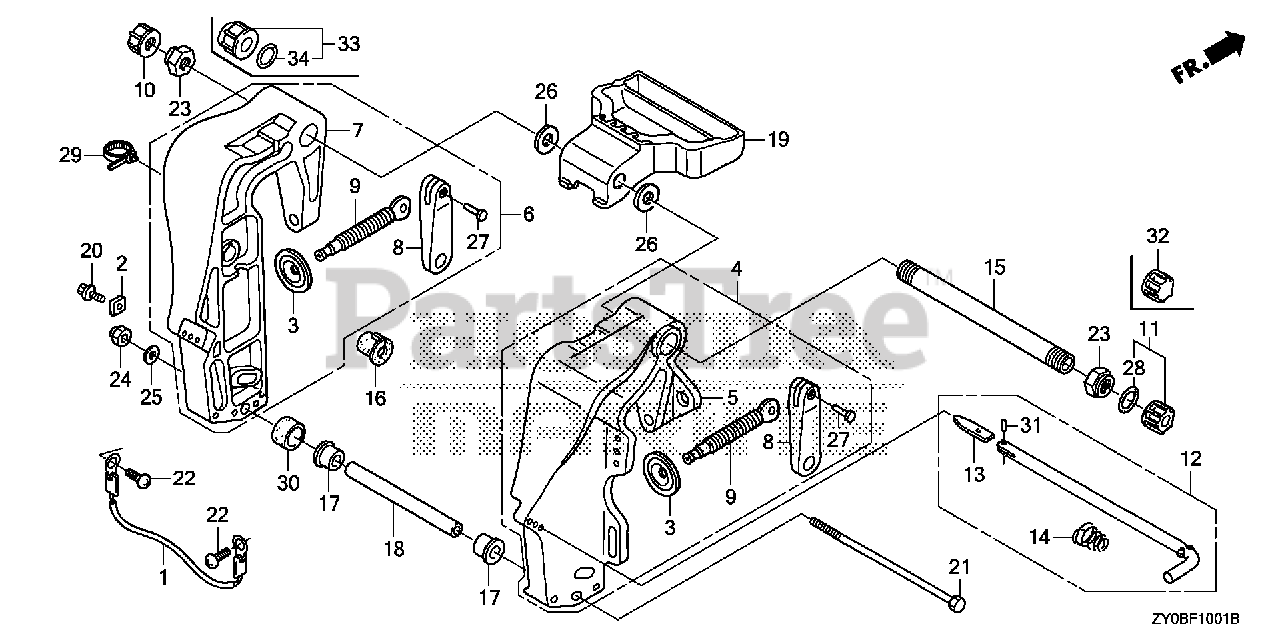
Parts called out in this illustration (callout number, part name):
1	WIRE, LEAD (1.5X170MM)
2	METAL, ANODE
3	PLATE, PUSH
4	BRACKET, R. STERN *NH282MU* (OYSTER SILVER METALLIC-U)
5	BRACKET, R. STERN *NH282MU* (OYSTER SILVER METALLIC-U)
6	BRACKET, L. STERN *NH282MU* (OYSTER SILVER METALLIC-U)
7	BRACKET, L. STERN *NH282MU* (OYSTER SILVER METALLIC-U)
8	GRIP, CLAMP
9	SCREW, CLAMP
10	CAP, TILTING BOLT
12	ROD, ADJUSTING
13	STOPPER, ROD
14	SPRING, ADJUSTING ROD
15	SHAFT, TILTING
16	BUSH, MOTOR CODE
17	BUSH, CYLINDER (LOWER)
18	COLLAR, CYLINDER (LOWER)
19	HANDLE, CARRYING REMOTE
20	BOLT, FLANGE (6X12) Use from Frame SN 1005249.
21	BOLT, HEX. (8X203)
22	SCREW, PAN (6X8)
23	NUT, SELF-LOCK (7/8-14UNF)
24	NUT, SELF-LOCK (8MM)
25	WASHER, PLAIN (8MM) Use up to Frame SN 4800712.
26	WASHER, WAVE (22MM)
27	RIVET (4X22.6)
29	CLIP, HARNESS BAND (145MM) (BLACK)
30	COLLAR, DISTANCE
31	PIN, SPRING (2.5X8)
32	CAP, TILTING BOLT
